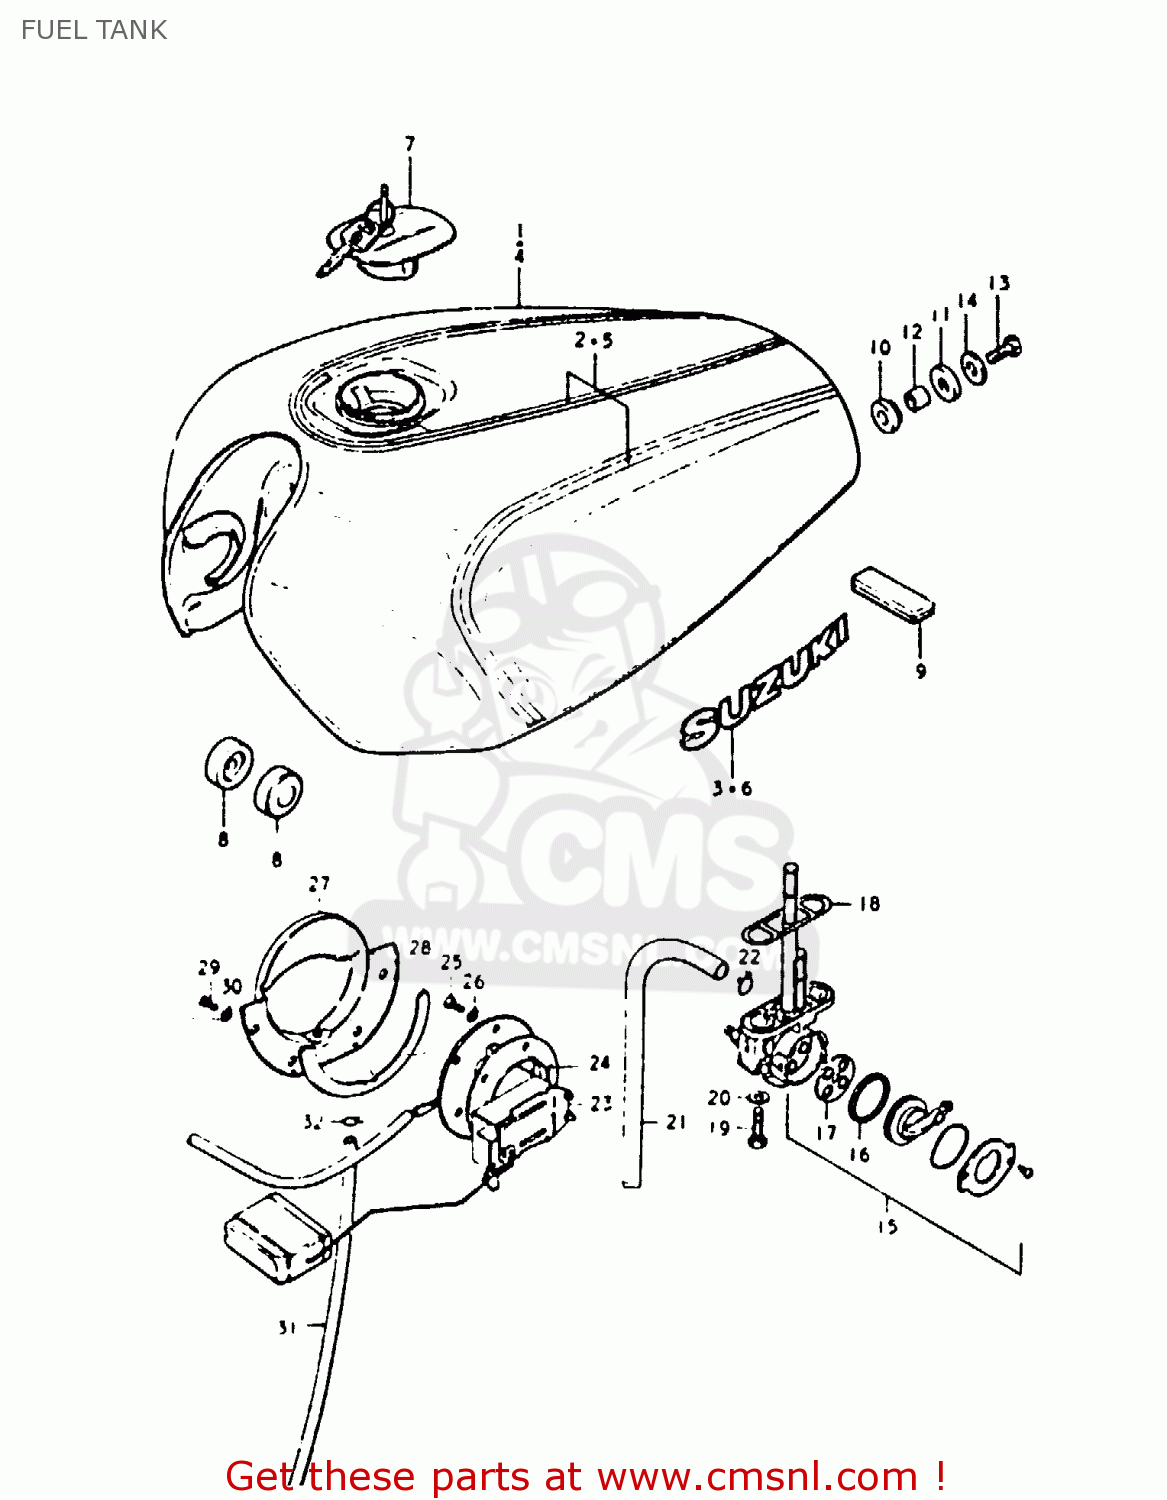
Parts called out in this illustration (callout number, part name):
1	TANK ASSEMBLY,FUEL
2	TAPE SET
3	EMBLEM
4	TANK, FUEL
5	TAPE SET
6	EMBLEM
7	CAP SET,FUEL TANK
8	CUSHION
9	CUSHION
10	CUSHION
11	CUSHION
12	SPACER(8.5X12X19)
13	BOLT (8X30)
14	WASHER (8.5X29X1.6)
15	COCK ASSY,FUEL
16	V SEAL,FUEL COCK
17	GASKET (NAS)
18	GASKET, FUEL COCK (NAS)
19	BOLT(6X20)
20	GASKET
21	HOSE
22	CLIP
23	GAUGE ASSEMBLY,FUEL LEVEL
24	GASKET,FUEL LEVEL GAUGE (NAS)
25	BOLT
26	LOCK WASHER
27	PLATE,FUEL DRAIN
28	GASKET,FUEL DRAIN PLATE (NAS)
29	SCREW
30	LOCK WASHER
31	HOSE
32	CLIP
